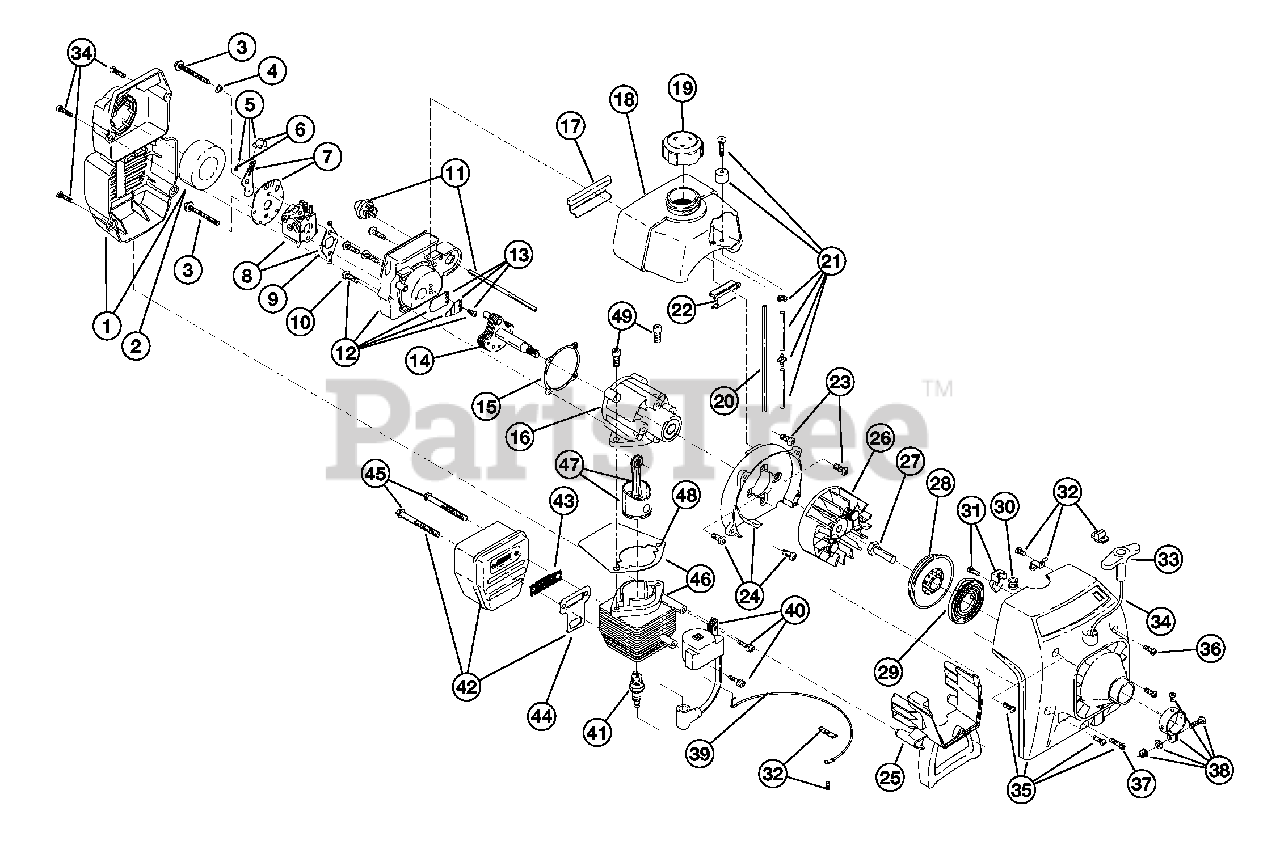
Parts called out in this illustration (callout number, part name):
1	Air Cleaner/Muffler Cover Assembly
2	Air Cleaner Filter
3	Carburetor Mounting Screw Assembly
4	Wavey Washer
5	Choke Lever Assembly
6	Choke Knob and Screw
7	Choke Lever and Plate
8	Carburetor Assembly
9	Carburetor Gasket
10	Carb Mount Screw
11	Primer and Hose Assembly
12	Carb Mount Assembly
13	Reed Assembly
14	Power Shaft Assembly
15	Crank Case Gasket
16	Crank Case Service Assembly
17	Rear Mounting Pad
18	Fuel Tank Assembly
19	Fuel Cap Assembly
20	Fuel Return Line
21	Fuel Line Assembly
22	Front Mounting Pad
23	Shroud Assembly
24	Shroud Screw
25	Shroud Extension and Stand
26	Flywheel Assembly
27	Square Nut Drive
28	Recoil Pulley Assembly
29	Recoil Spring
30	Rope Guide
31	Pulley Retainer Assembly
32	Switch Assembly
33	Pull Handle
35	Starter Housing Assembly
36	Housing Screw
37	Cover Screw
38	Upper Clamp Assembly
39	Wire Lead
40	Module Assembly
41	Spark Plug
42	Muffler Assembly
43	Spark Arrestor
44	Exhaust Gasket
45	Muffler Mounting Bolt Assembly
46	Cylinder Assembly
47	Piston and Rod Assembly
48	Cylinder Gasket
49	Cylinder Bolt
